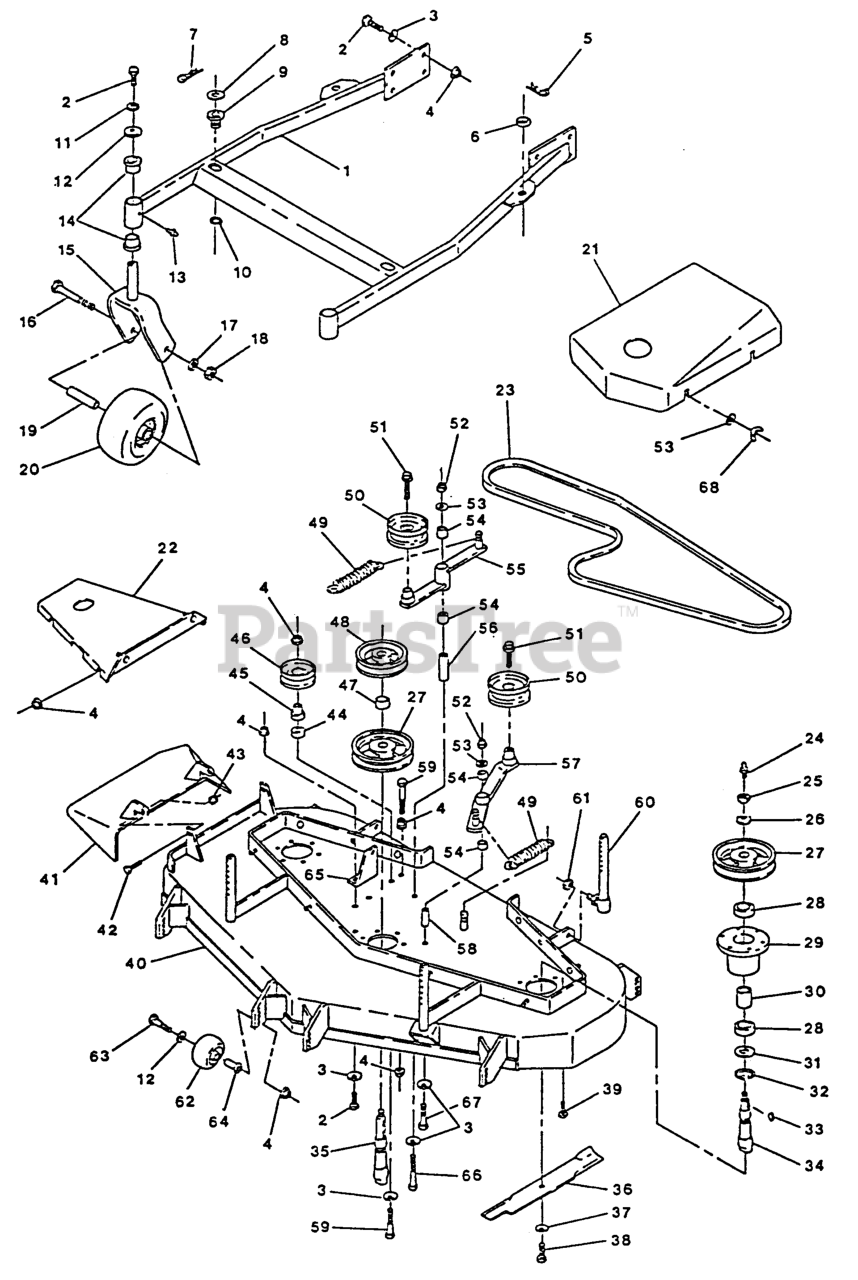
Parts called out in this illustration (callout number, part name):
5	PIN,HAIR COTTER
8	WASHER-FLAT
9	BUSHING-DECK
23	BELT,BLADE DRIVE
26	WASHER-SPRING
27	SHEAVE,BLADE DRIVE
30	SPACER,BEARING
31	SEAL,MECHANICAL DUST
32	RING,SNAP WLDS N5000-244
34	SPINDLE-OUTER BLADE
35	SPINDLE-CENTER BLADE
37	WASHER-SPRING
39	SCRW,TPTTE HH
41	WLD,CHUTE DISCHARGE
47	SPACER-TUBE
48	SHEAVE,MOWER DRIVE
49	SPRING-EXTENSION
50	IDLER,PULLEY
54	SLEEVE-BEARING
55	ASM,IDLER ARM
56	BUSHING-PIVOT, IDLER
58	BUSHING
62	ROLLER-SCALP, ANTI
63	SCRWCAPHH
64	BUSHING-ROLLER
65	BRACKET,SPRING ANCHOR
66	SCREW-HH
68	NUT-WING
